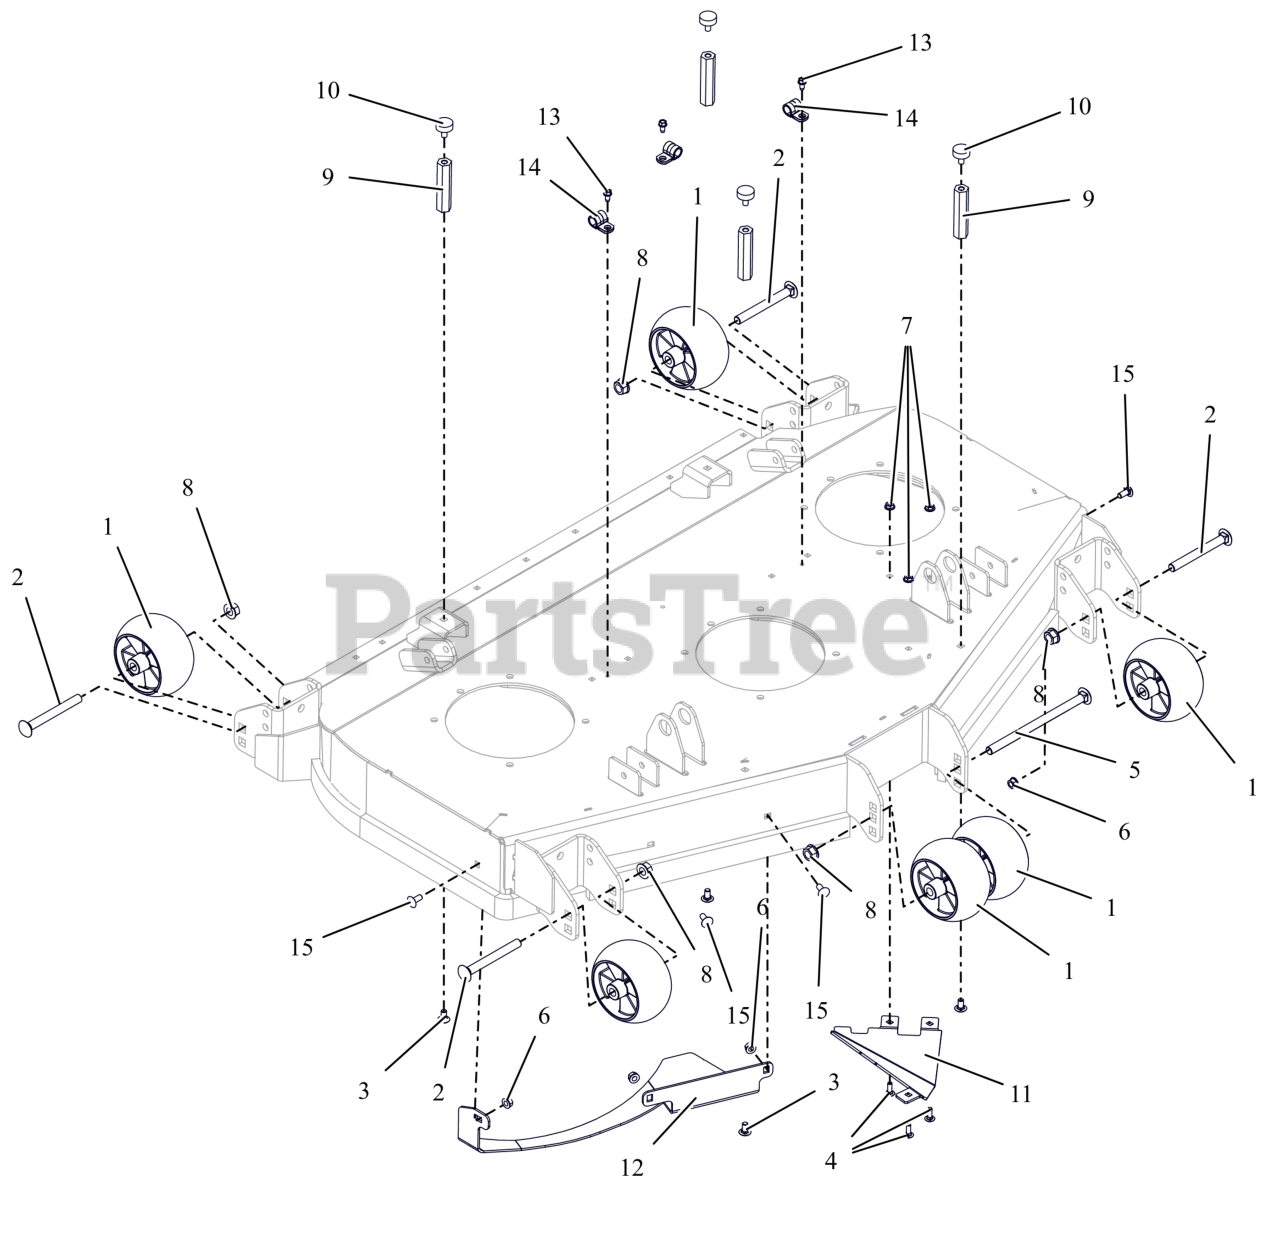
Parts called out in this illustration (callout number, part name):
1	WHEEL, ANTI SCALP - 5X3 CTR W/RIBS
2	BLT,RHNS .50-13X4.50 G5 ZCC NS
3	BTL,RHSSN .313-18 X 0.625 G5 ZCC
4	BLT, RHSN .25-20X.750 G5 ZCC
5	BLT,RHSN .50-13X8.00 G5 ZCC NS
6	NUT,LK-CTR-FLG .31-18 GF ZCC
7	NUT-LK-CTR-FLG .25-20 ZC120
8	NUT-LK-CTR-FLG .500-13 GG ZCC
9	NUT, COUPLING .312-18 X 3.375
10	BUMPER, RUBBER
11	BAFFLE, 48" TRIANGLULAR INSERT (RED)
12	DEFLECTOR, BAFFLE BOLT-IN (RED)
13	SCR-TAP .25-20X.50 HWH ZCC
14	CLAMP, CUSHIONED STEEL
15	BLT, RHSSN.31-18X.750 G5 ZCC
